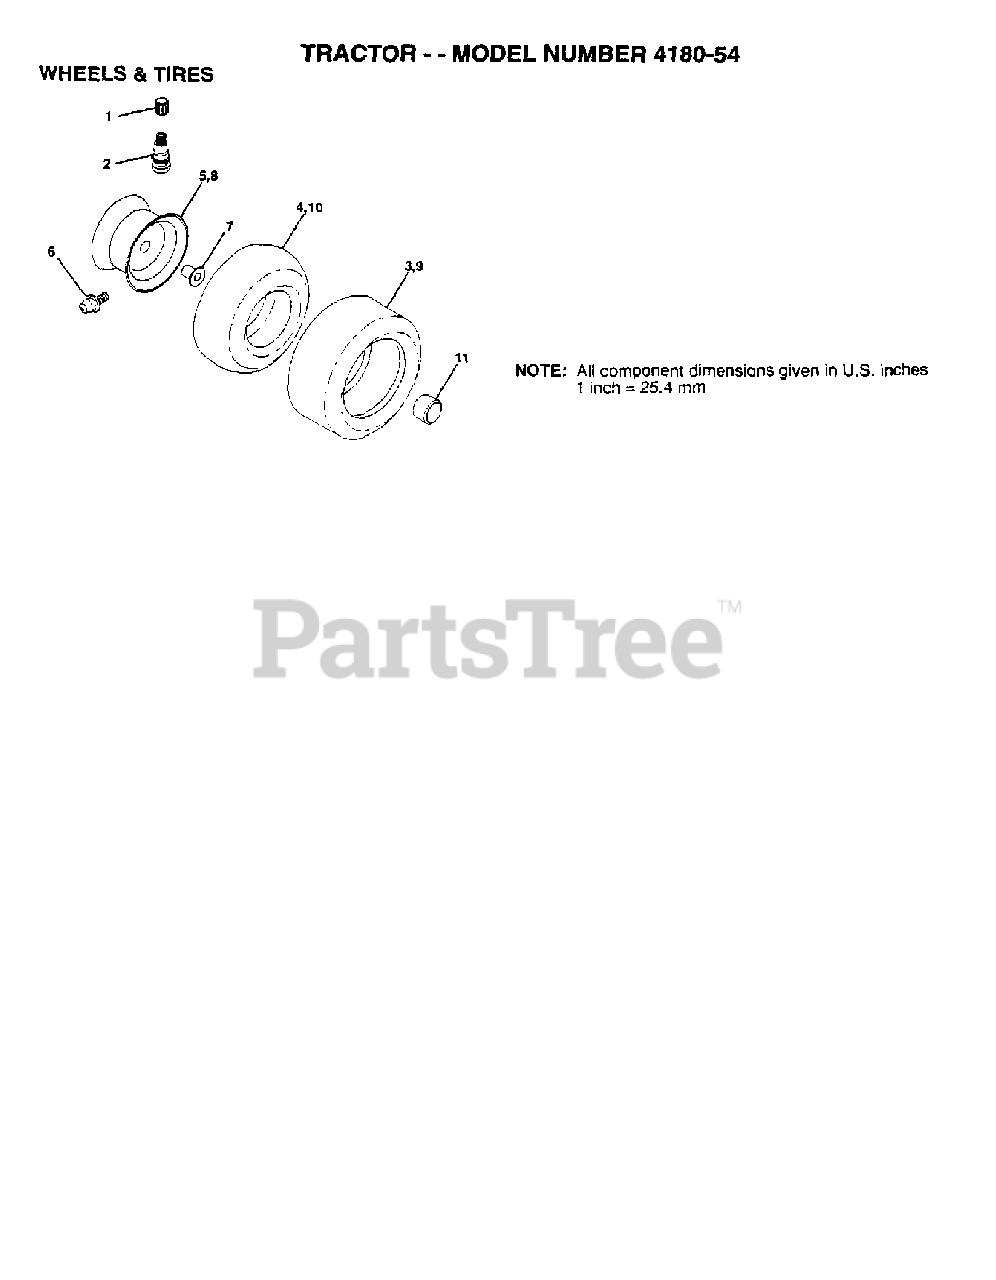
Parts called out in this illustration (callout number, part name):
1	VALVE CAP
2	VALVE STEM LT
3	TIRE HEAVY DUTY
4	TUBE.5.3/4.5/6
5	Rim Assembly, 8 X 5 Front Silver
6	FITTING LT
7	BEARING T
9	Tire, .23 X 8.5-12 Turf Saver
10	TUBE.23"X9.5""X12""
11	CAP.HUB.FRONT.LT.BLACK
